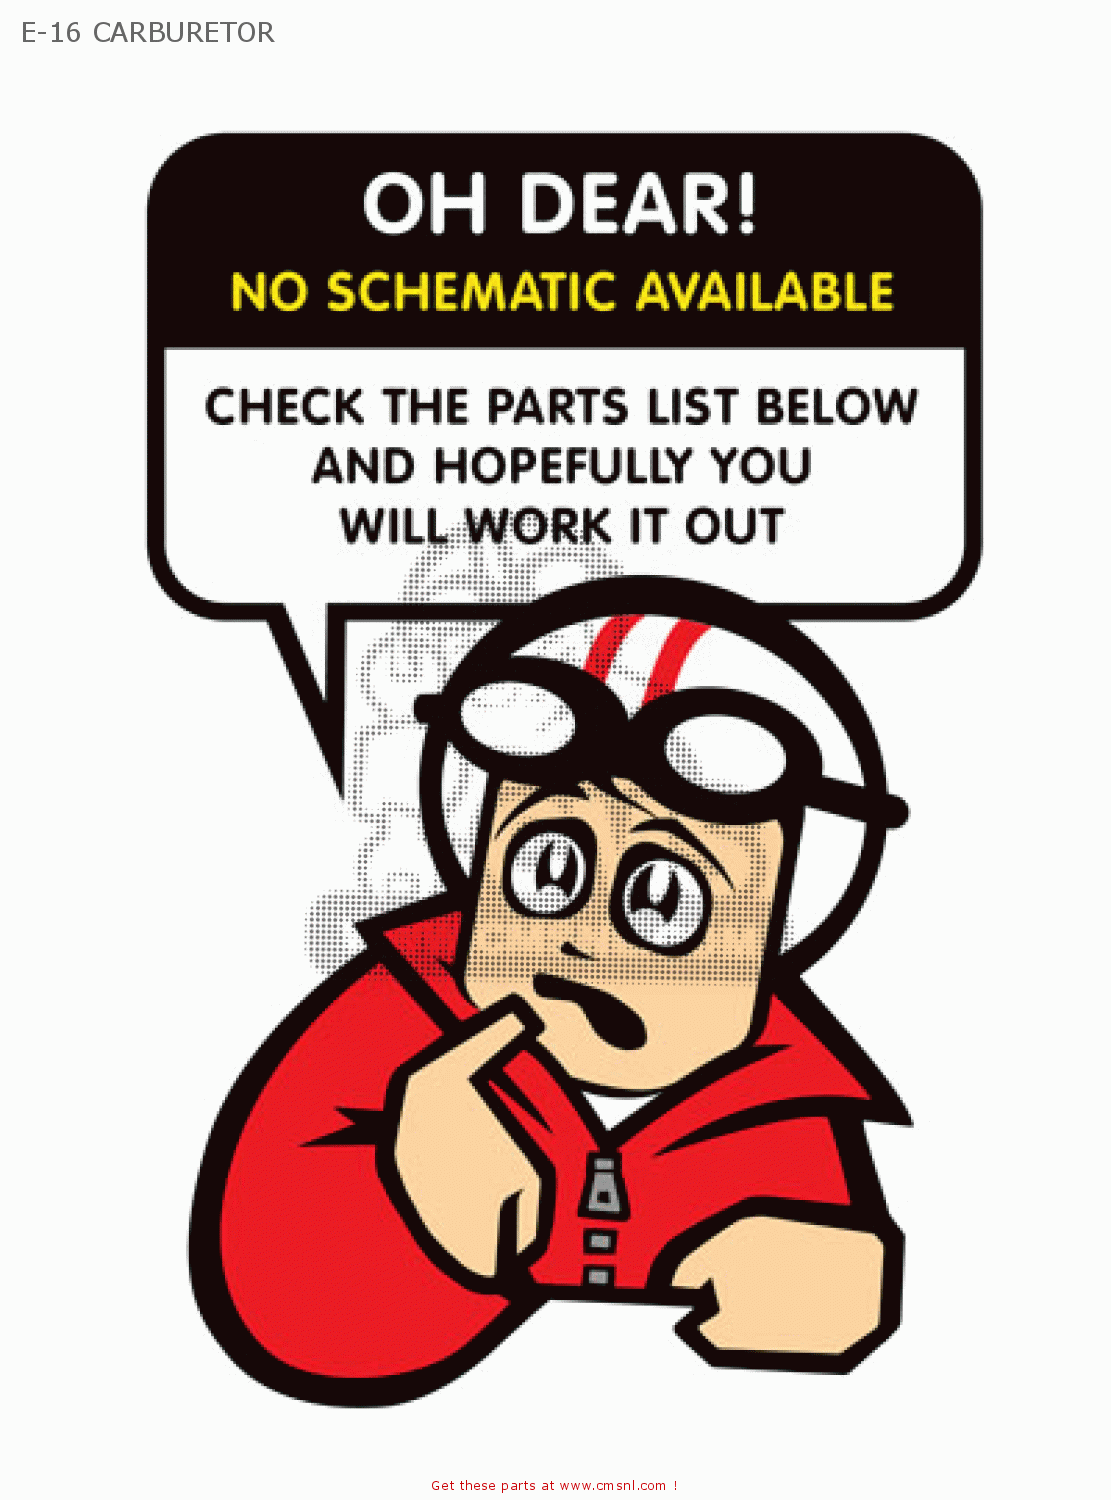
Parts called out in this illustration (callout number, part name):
1	FENDER,RR
2	WASHER,FR FENDER
3	BOLT
4	NUT,RR REFLECTOR
5	BOLT
6	EMBLEM,RR FENDER
7	OPEN SPANNER(6.4X6.8)
